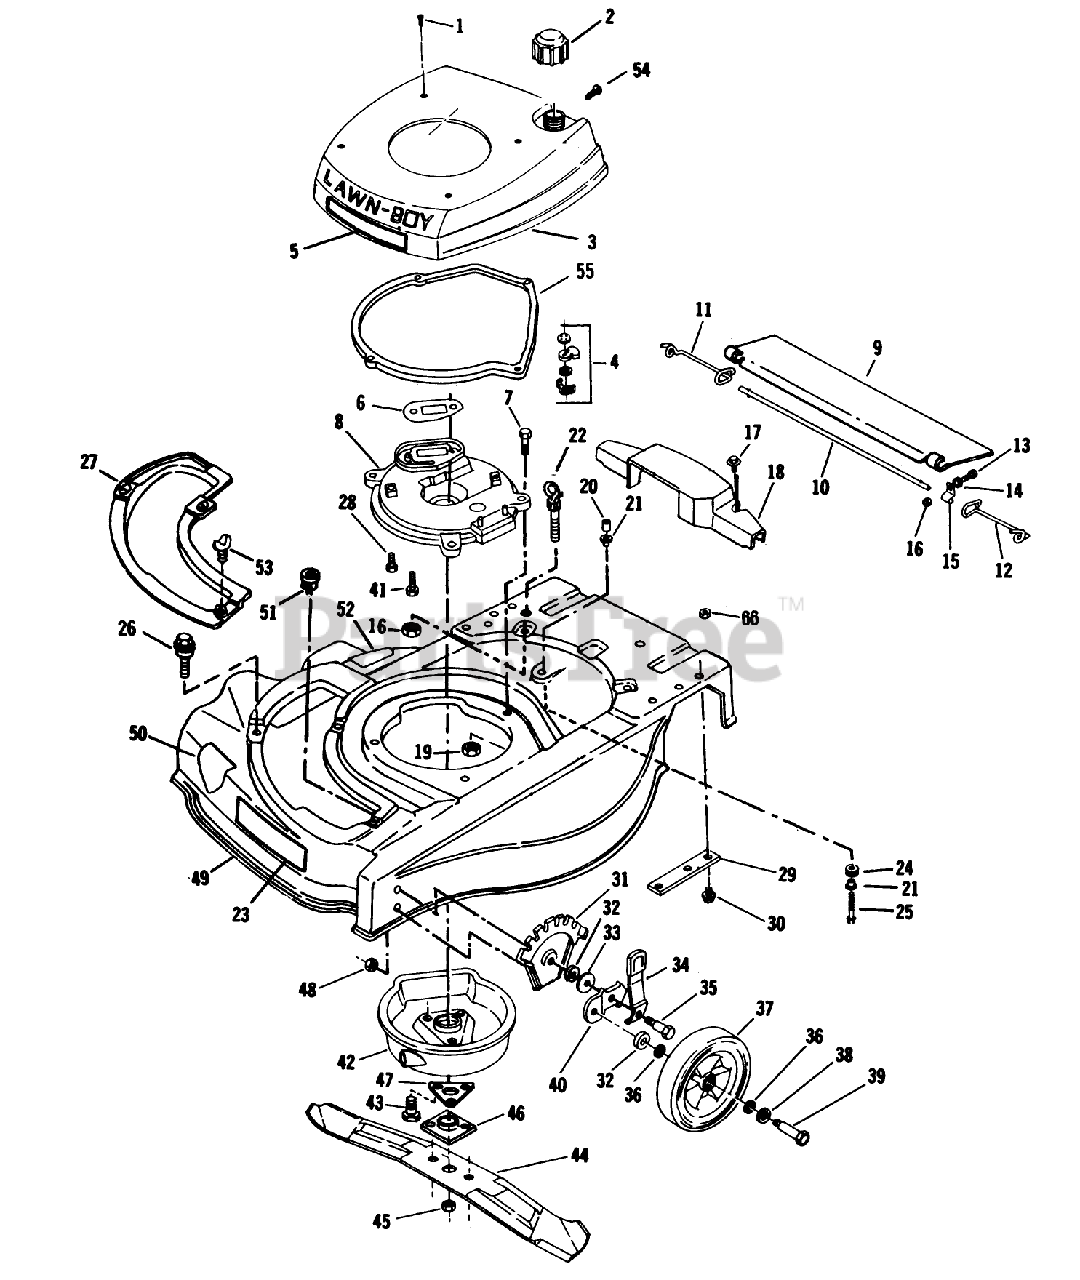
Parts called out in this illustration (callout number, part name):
1	SCREW LAWRENCE
7	SCREW-HH
8	PLATE,MUFFLER F
10	ROD T/SHIELD ADV WIRE
11	SPRING;TRAILING SHIELD RH
12	SPRIG T/SHLD ASOC
14	Washer-Trailing Shield
15	CLAMP ROD KMC
16	LOCKNUT E
17	SCREW SEMS TRM HEX HD
19	NUT-LOCK F
21	SPACER ECK PRES
22	BOLT-EYE
31	PLATE HGT ADJ TRO
32	WASHER WROUGHT
34	KNOB&SPRING FORMCO
37	WHEEL & TIRE KIT
39	BOLT WHEEL
41	SCREW V
45	NUT-BLADE
46	PLATE AND COLLAR ASM
47	SUPPORT F
48	LOCKNUT
53	WING SCREW LAWRE
54	SCREW S
